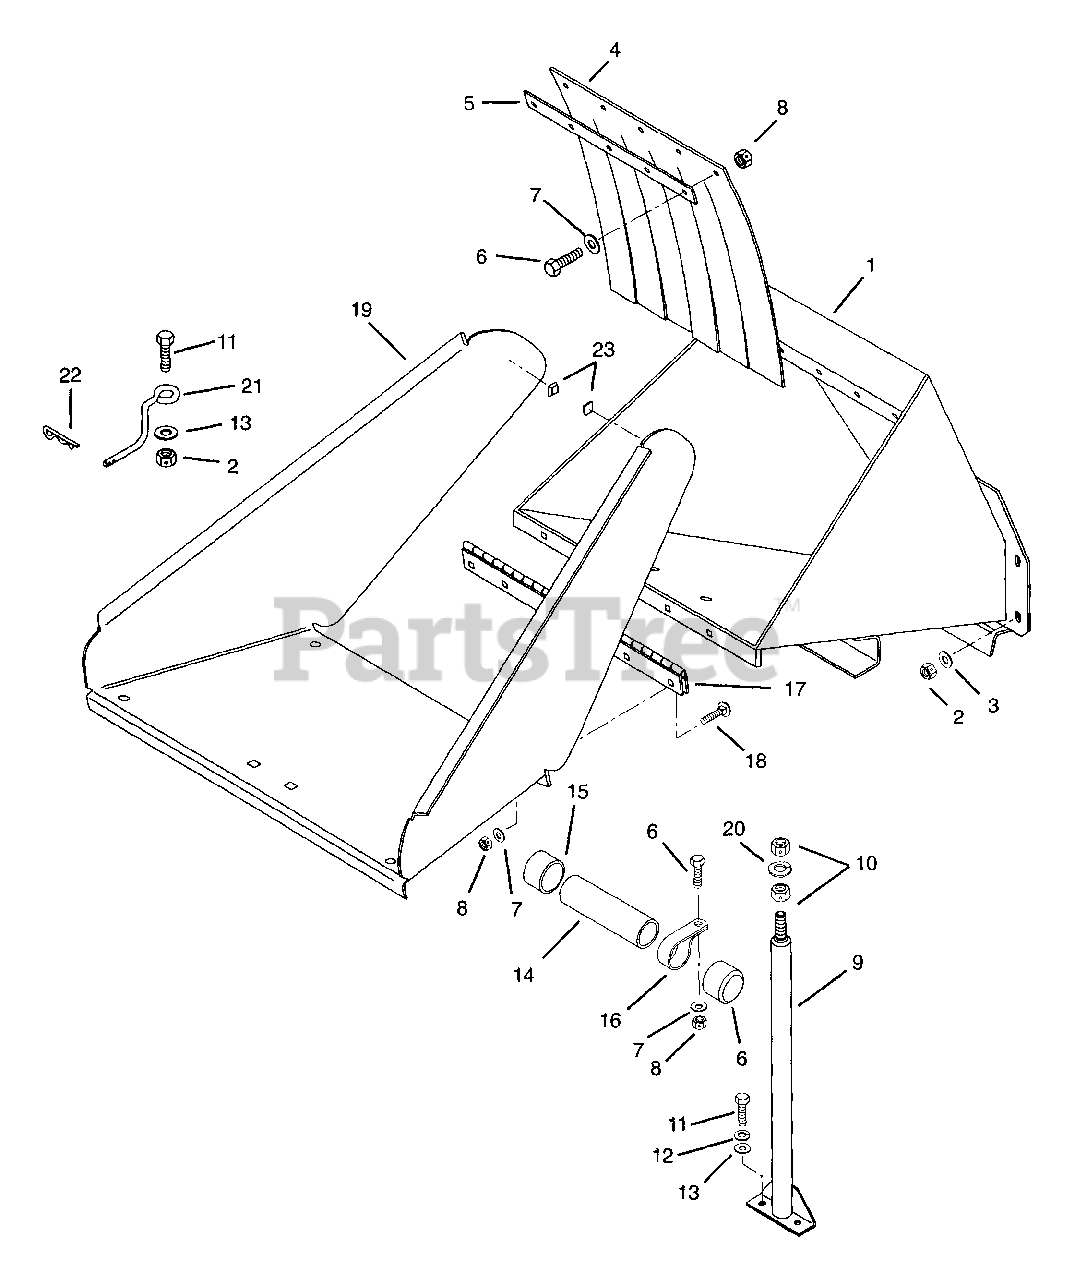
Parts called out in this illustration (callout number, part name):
1	Hopper
2	Nut-Locking-Center .38-16
3	Washer-Flat-Steel .406 x 1.00 x .188
4	Flap-Protective
6	Bolt-Hex .25-20 x .75 Grade 5
7	Washer-Flat-Steel .312 x .734 x .065
8	Nut-Locking-Center .25-20
9	Hopper Stand
10	Nut-Locking-Center .75-10
11	Bolt-Hex .38-16 x 1.00
12	Washer-Lock .38 x .094
13	Washer-Flat-Steel .438 x 1.00 x .083
14	Plastic Tube, Instructions
15	End Cap, Instruction Tube
18	Bolt-Round Head Square Neck .25-20 x .50 Grade 5
19	Safety Bonnet
20	Washer-Locking .75 x .188
21	Bonnet Positioner
22	Pin-Hair-Internal .15 x 2.937
